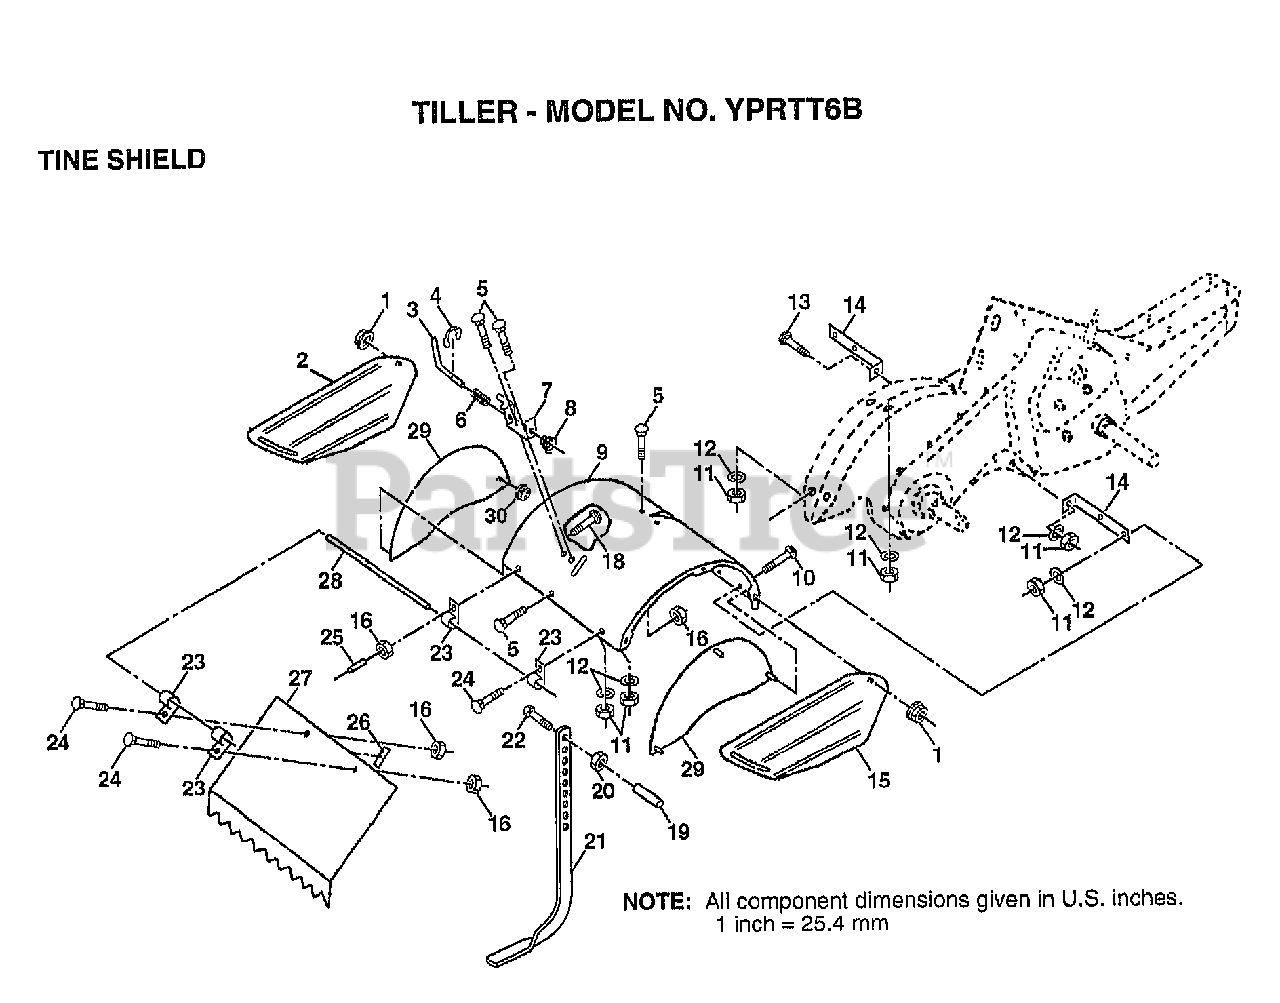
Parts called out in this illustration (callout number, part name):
1	NUT
2	SHLD.SIDE.OUTER.L
3	STAKE PIN TI
4	KLIP RING TI
5	BOLT
6	SPRING TI
7	LATCH BRACKET TI
8	SPRING CRT
9	SHIELD TINE
10	BOLT
11	NUT.HEX.5/16-18
12	LOCKWASHER
13	BOLT
14	"BRACKET,SHIELD"
15	SHLD.SIDE.OUTER.R
16	NUT
18	BOLT
19	GRIP CRT
20	NUT.HEX.3/8-16UNC
22	BOLT
23	HINGE CRT
24	BOLT
25	VINYL CAP TI
26	PAD IDLER TI
27	"SHIELD,LEVEL"
28	PIN HINGE
29	SHIELD TINE
30	LOCKNUT TI
